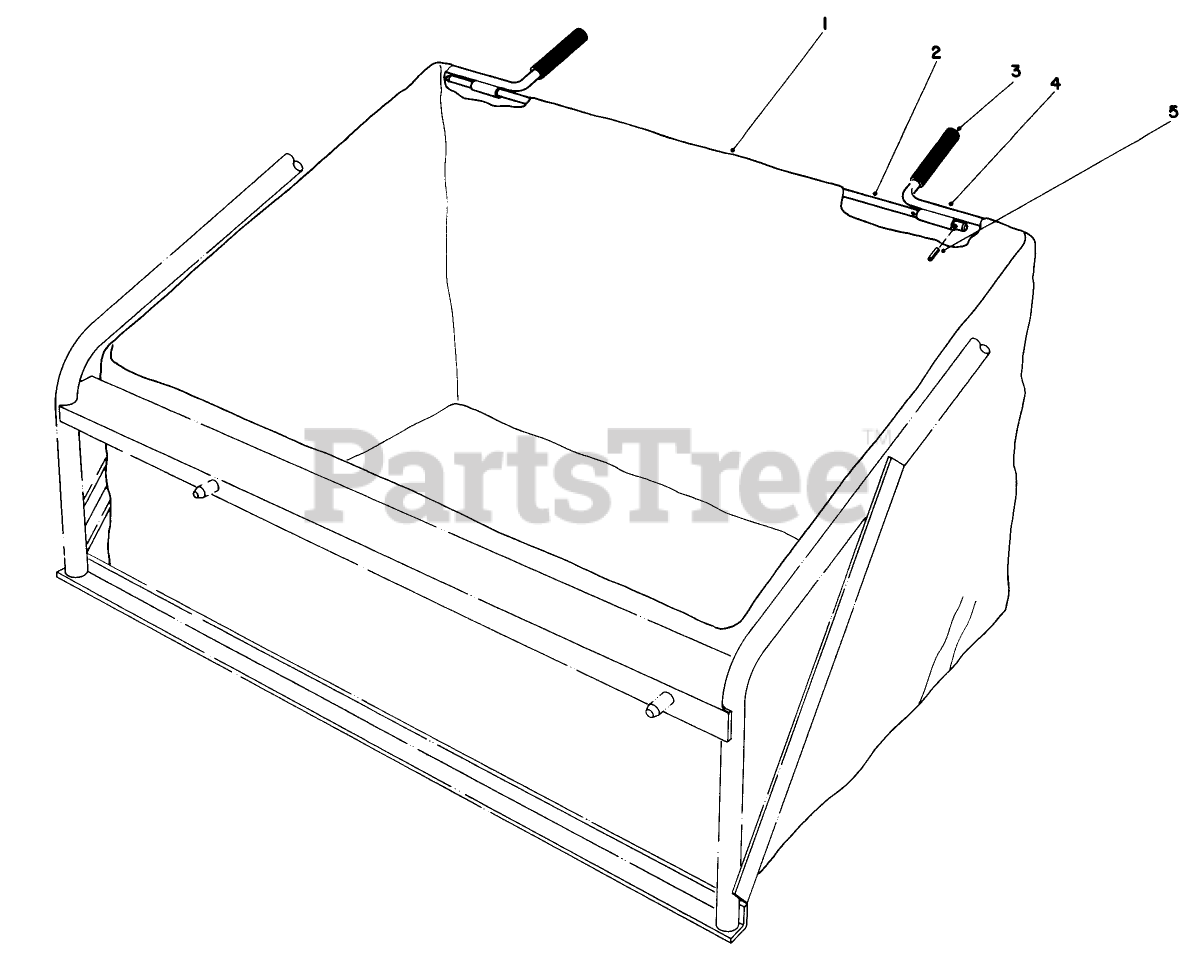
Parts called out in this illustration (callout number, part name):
1	Bag-Leaf Catcher
2	Rod-Bag Frame
4	BAG FRAME WA *B
5	PIN-ROLL
